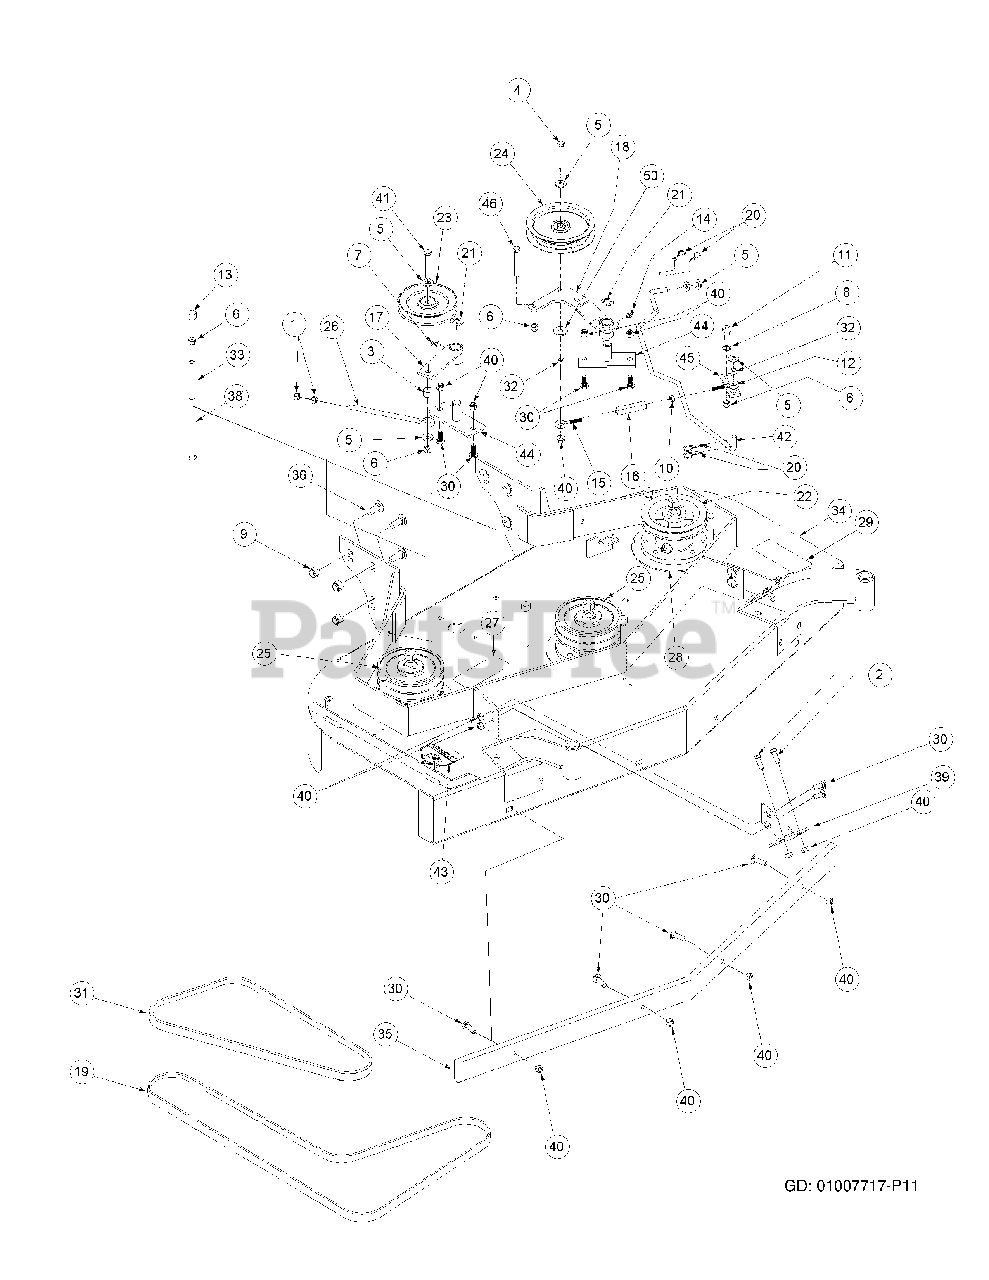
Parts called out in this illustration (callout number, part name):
1	Hex Nut, 3/8-16
2	Hex Cap Screw, 3/8-16, 1
3	Sleeve Tensioner
4	Washer, 1.25 x .411 x .100
5	Flat Washer, 3/8 Zinc
6	Lock Nut, Nylon Insert, 3/8-16
7	Grease Fitting, 1/4-28, 90°
8	Shim Washer
9	Nut, Flange Lock, 1/2-13
10	Hex Nut, 5/16-18
11	Shoulder Bolt
12	Eye Bolt, Right Hand
13	Vinyl Cap
14	Grease Fitting, 45°, 1/4-28
15	Eye Bolt, Left Hand
16	Turnbuckle
17	Idler Arm "B"
18	Idler Arm "A"
19	Drive Belt
20	Hair Pin, 3/8"-1/2"
22	Deck Pulley
23	Idler Pulley
24	Idler Deck Take-up
25	Double Pulley
26	Rod Belt Tensioner
27	Decal Rotating Blade
28	Spindle Backing Plate
29	Decal Warning Shield Missing
30	Carriage Screw, 3/8-16 x 1-1/4
31	Drive Belt
32	Sleve Turnbuckle
33	Spacer Belt Guide
36	Carriage Bolt, 1/2-13 x 1-1/4
37	Hex Cap Screw, 3/8-16, 2.75
38	Carriage Bolt, 3/8-16 x 4-1/2
39	Caster Support Assembly
40	Hex Nut Flange Lock, 3/8-16
41	Hex Cap Screw, 3/8-16, 2.25
42	Rod Clutch Link
43	Decal, Danger Hands and Feet
44	Idler Base
